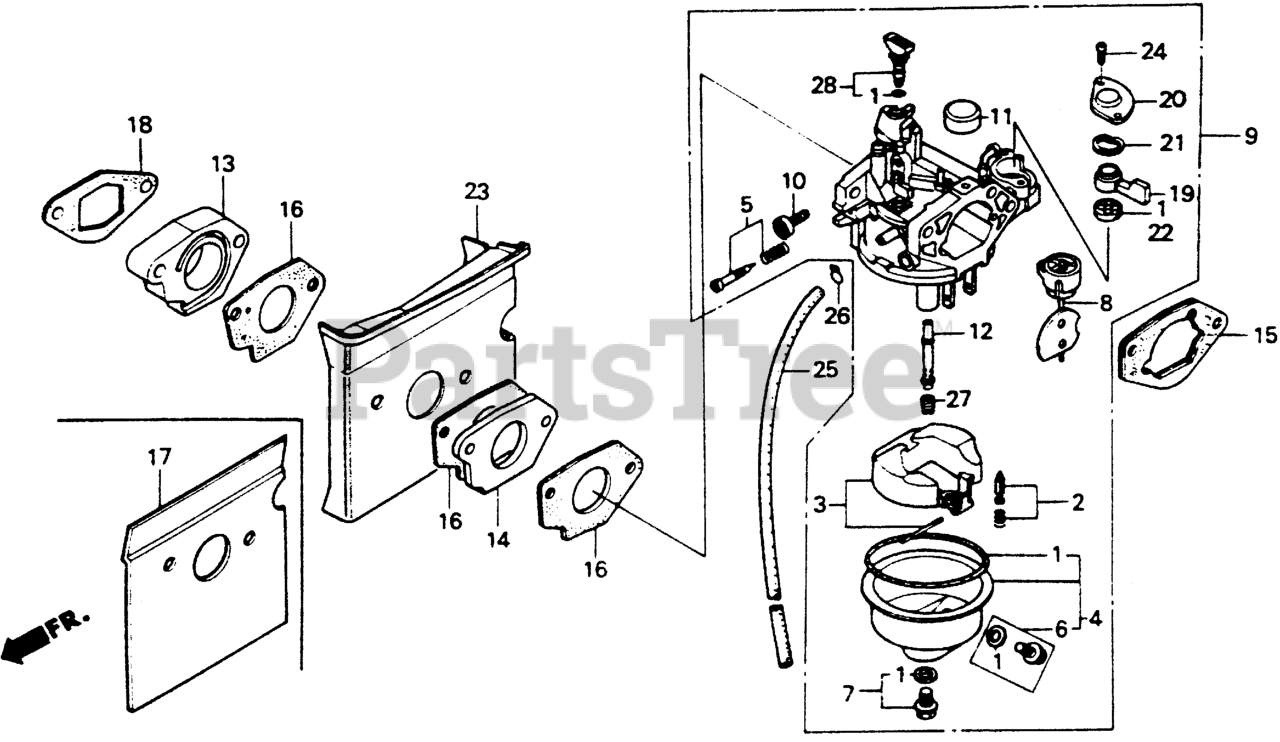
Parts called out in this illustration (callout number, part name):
1	GASKET SET
1	GASKET SET (EXC. 16173-001-004) (CARBURETOR NO.) (EXCEPT 16173-001-004)
2	VALVE SET, FLOAT
3	FLOAT SET
4	CHAMBER SET, FLOAT
5	SCREW SET, PILOT
7	SCREW SET B
7	SCREW SET
9	CARBURETOR ASSY. (BE23B B)
9	CARBURETOR ASSY. (BE23B C)
10	SCREW, THROTTLE STOP
11	CAP, CHOKE LEVER DUST
12	NOZZLE, MAIN
13	INSULATOR, CARBURETOR
14	INSULATOR, CARBURETOR
15	SPACER, CARBURETOR
16	GASKET, CARBURETOR
18	GASKET, INSULATOR (Honda Code 2090074). (NOT AVAILABLE)
19	LEVER, VALVE
20	PLATE, LEVER SETTING (CARBURETOR NO.)
21	SPRING, PETCOCK LEVER (CARBURETOR NO.)
22	GASKET, VALVE
23	GUIDE, AIR
24	SCREW, PAN (3X8)
25	BULK HOSE, FUEL (4.5X3000) (Honda Code 5137104). (4.5X140)
26	CLIP, TUBE (B8)
27	JET, MAIN (#80)
27	JET, MAIN (#85)
27	JET, MAIN (#82)
28	JET SET, PILOT (#45)
